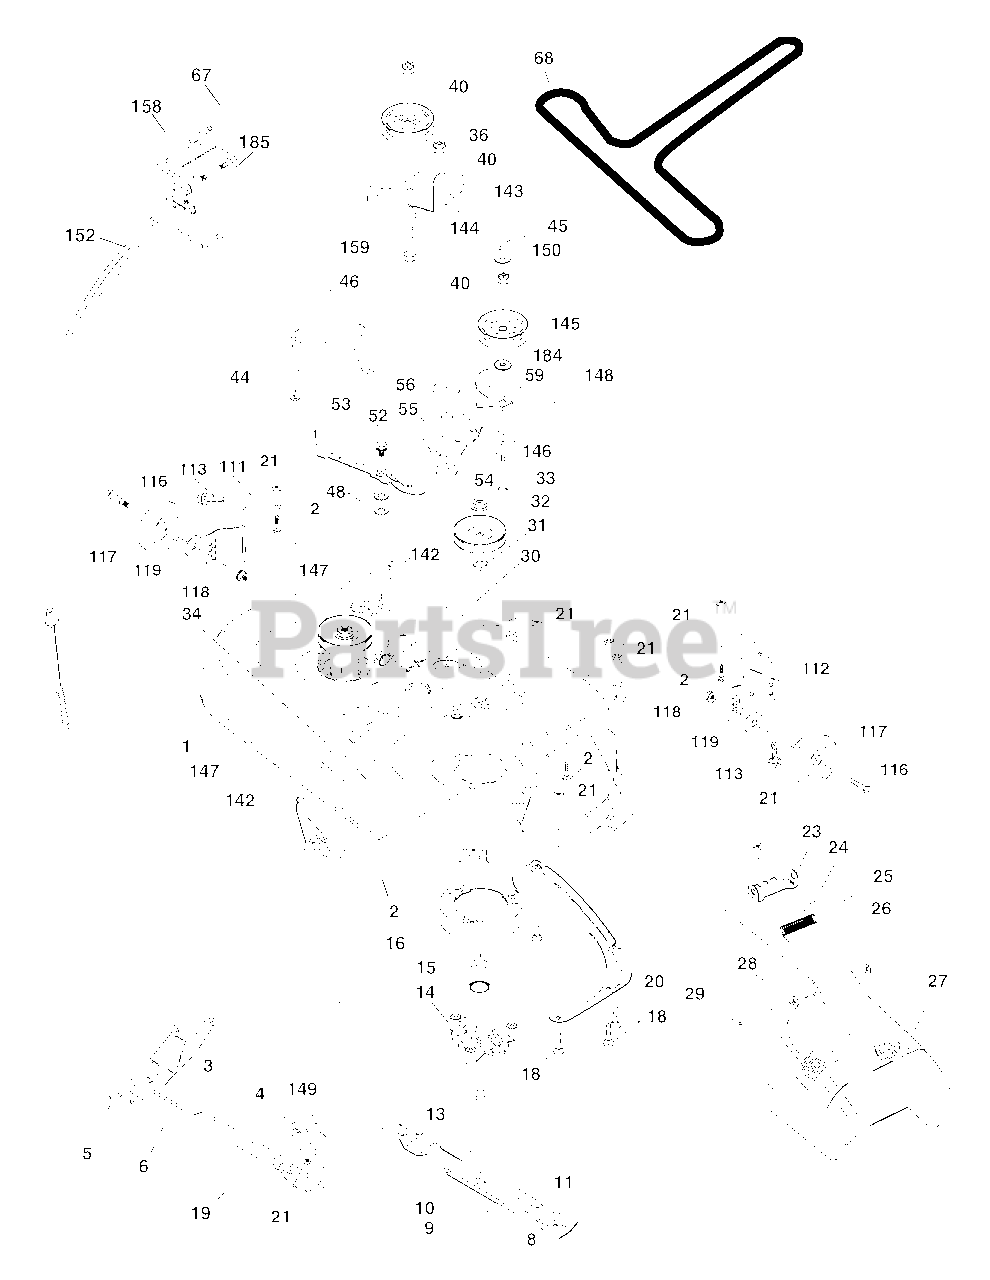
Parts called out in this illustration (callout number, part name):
1	Mower Deck Assembly, 42"
2	Bolt
3	Bracket Asm Fr. Sway Bar 3/42
4	Bracket Asm Deck 42" Sway Bar
5	Retainer Spring
6	Bar Sway Deck
8	Bolt 3/8-24 x 1.25 Gr. 8 patched
9	Washer, Lock
10	Washer, Hardened (The following Blades are available)
11	Blade Mower 42" Hi-Lift
13	Shaft Assembly, Mandrel, Vented
14	Housing, Mandrel, Vented
15	Bearing, Ball, Mandrel
16	Stripper, Mandrel Deck
18	Bolt, Carriage 5/16-18 x 5/8
19	Bolt, Shoulder
20	Baffle, Vortex
21	Nut
23	Bracket, Deflector Mower 42"
24	Cap, Sleeve 80 x 112 Blk Mower
25	Spring, Torsion, Defl ector 2 52
26	Nut, Push Phos & Oil
27	Shield, Defl ector 42" Blk
28	Washer 11/32 x 5/8 x 16 Ga.
29	Rod, Hinge 42" 6 75 W/G
30	Screw Thdrol
31	Washer, Spacer Mower Vented
32	Pulley, Mandrel
33	Nut, Toplock
34	Bolt Carr SH 3/8-16 x 1-1/2 Gr.5
36	Pulley, Idler, Flat
40	Nut Lock 3/8-16
44	Guard, Mandrel, LH
45	Retainer
46	Screw, Thdrol 1/4-20 x 5/8 T
48	Washer, Hardened
52	Bolt, Shoulder 5/16-18 unc
53	Arm Assembly, Pad, Brake
54	Washer, Hardened
55	Arm, Idler
56	Spacer, Retainer
59	Guard TUV Idler
67	Knob Round
68	V-Belt, 42" Mower
111	Bracket Asm. Whl Ga. LH
112	Bracket Asm Whl Ga. RH
113	Screw 5/16-18
116	Bolt, Shoulder
117	Wheel, Gauge
118	Nut Centerlock 3/8-16
119	Washer 3/8 x 7/8 x 14 Ga.
142	Arm Spring Brake Mower
143	Bracket Arm Idler 42"
144	Keeper Belt 42" Clutch Cable
145	Pulley Idler Flat
146	Bolt Carriage Idler
147	Spring Extension
148	Spring Return Idler
149	Retainer Spring Yellow
150	Washer 9/32 x 3/4 x 10 Ga.
152	Clutch Cable 42"
158	Screw Hex Thd Cut 1/4-20 x 1/2
159	Bolt Rdhd Sqn 3/8-16 unc x 1-3/4
184	Washer 13/32 x 7/8 x 10 Ga.
185	Head Asm Cable Clutch
